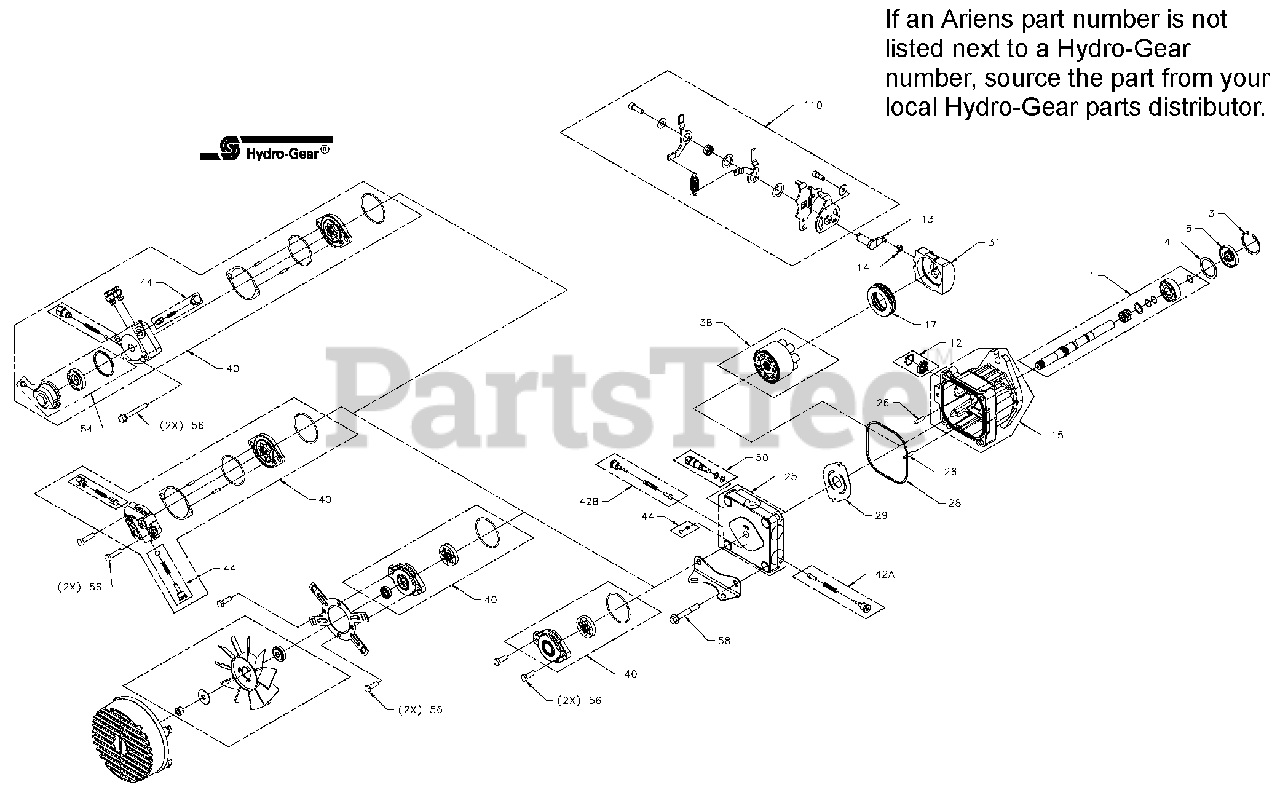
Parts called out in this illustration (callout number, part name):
1	Kit, Pump Shaft
3	Ring, Ret 47 Int
4	Washer, 1.45 x 1.84 x .04
6	Seal, Lip 17 x 47 x 8
12	Kit, Bdp-16a Trunnion Seal
13	Arm, Trunnion
14	Guide, Slot
15	Service Kit, Housing
17	Bearing, Thrust Ball 42 x 68 x 16
25	Kit, End Cap
26	Pin, .219 x 1
28	O-Ring, Square 1 x (4.3 x 4.6)
29	Valve Plate
31	Plate, Swash 21cc
38	Kit, Motor Block
42	Kit, Shock Valve 200 Bar
50	Kit, Bypass Valve
54	Kit, Auxiliary Filter
56	Hfhcs 5/16-18 x 2.5
58	Kit, Bolt
110	Kit, Return
